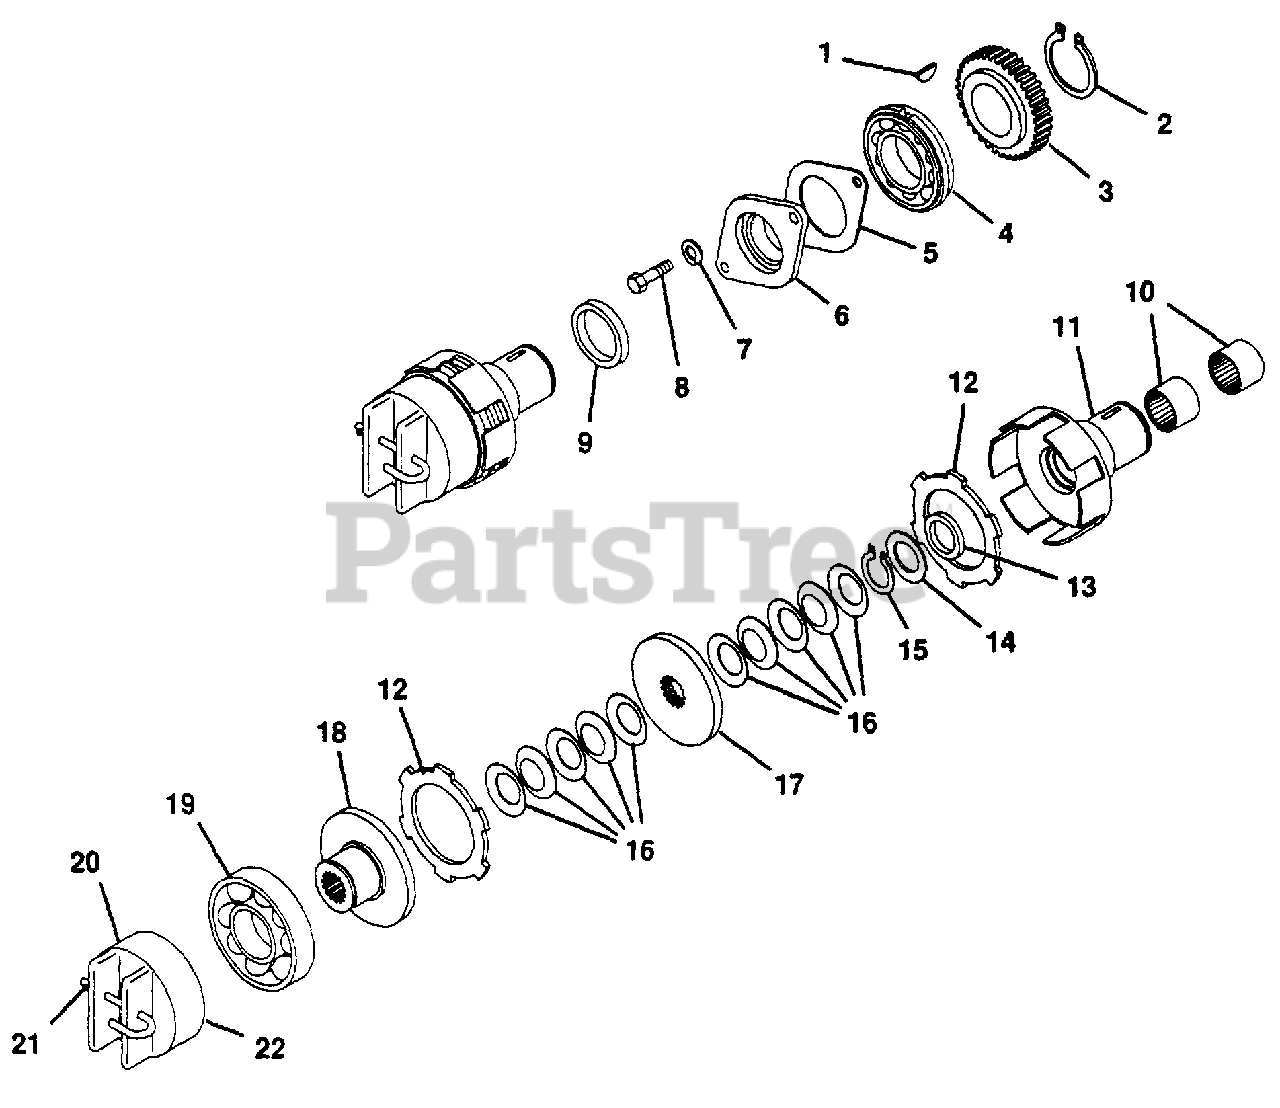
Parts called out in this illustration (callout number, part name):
1	Key, Woodruff .250x1.00 Hrd #15
2	Ring, Retaining 1.969 Shaft
3	Gear, PTO Input
4	Bearing, Ball 1.968x3.149x.63
5	Gasket, Front PTO Cap
6	Cap, Front PTO
7	Washer, Lock 5/16 Reg.
8	Bolt, Hex 5/16-18x.75
9	Seal, Oil 2.250x3.005x.375
10	Bearing, Roller
11	Hub, PTO Clutch
12	Disc, Clutch
13	Seal, Oil 1.000x1.500x.250
14	Race, Brg Thrust .752x1.240x.030
15	Ring, Retaining .08 Thick
16	Spring, Belleville
17	Plate, Clutch
18	Hub, Clutch Actuating
19	Bearing, Ball 1.574x3.149x.70
20	Trunion, Fwd-Rev Clutch
21	Pin, Cotter .06x.75
22	Pin, Clutch Spring
